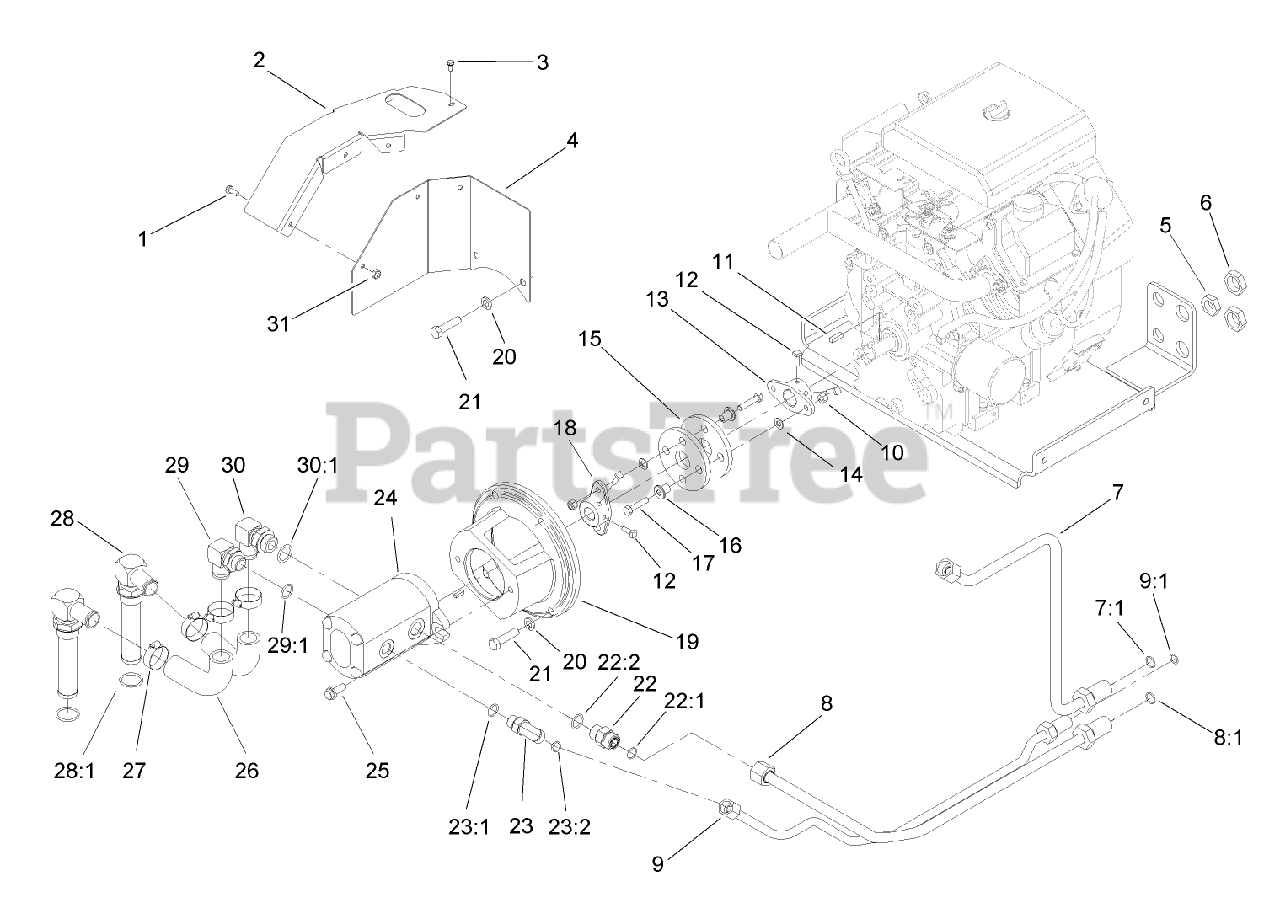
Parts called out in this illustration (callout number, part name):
1	SCREW-HH
2	SHIELD-HEAT
3	SCREW-HWH
4	SHIELD-HEAT
5	NUT-BULKHEAD
6	NUT-LOCK, BULKHEAD
7	HYD TUBE ASM
7:1	O-RING
8	HYD TUBE ASM
8:1	O-RING
9	HYD TUBE ASM
9:1	O-RING
10	NUT-LOCK, NI
11	KEY-SQUARE
12	SCREW-SQH
13	HUB-ENGINE
14	WASHER-PLAIN
15	COUPLING-RUBBER
16	SPACER
17	SCREW-HH
18	HUB-PUMP
19	MOUNT-PUMP
20	WASHER-LOCK
21	SCREW-HH
22	FITTING-STRAIGHT
22:1	O-RING
22:2	O-RING
23	FITTING-ELBOW-90 DEG
23:1	O-RING
23:2	O-RING
24	HYD PUMP ASM
25	SCREW-HHF
26	HOSE-SUCTION, FORMED
27	CLAMP-HOSE
28	STRAINER FITTING ASM
28:1	O-RING
29	STEM-HOSE, 90 DEG
29:1	O-RING
30	FITTING-HYD, 90 DEG
30:1	O-RING
31	NUT-LOCK, NI
